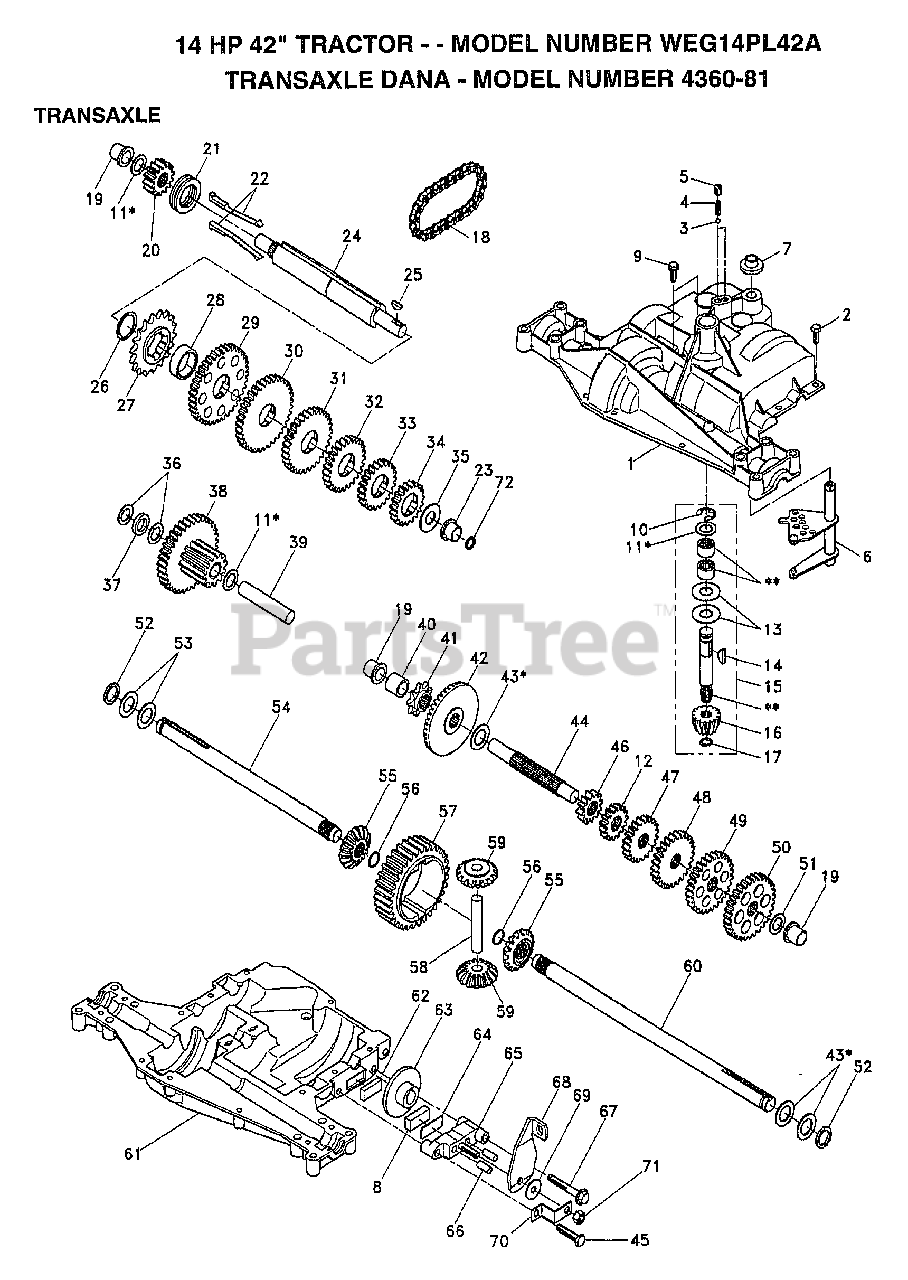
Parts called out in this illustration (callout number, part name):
1	HOUSING, UPPER
3	BALL, DETENT
4	SPRING, DETENT
5	SCREW, SET
6	KIT, SHIFTER ASSEMBLY
7	BOOT, SHIFTER
8	PUCK, FRICTION
9	SCREW TAPPING WITH SEALER
10	RING, RETAINING
11	ASSY, KIT, SHIM .625 SHAFT
12	GEAR, SPUR, 15T
13	WASHER, PLAIN .632 X 1.38 X .046
14	KEY, WOODRUFF, #9
15	ASSY KIT INPUT SHAFT
16	PINION BEVEL 14 TEETH
17	RING, RETAINING
18	CHAIN, 24 PITCHES
19	BEARING, FLANGE
20	GEAR, SPUR, 14 TEETH
21	COLLAR, CLUTCH
22	ASSY, KIT, CLUTCH KEYS
23	BEARING, FLANGE
24	SHAFT, INTERMEDIATE
25	KEY, WOODRUFF, #61
26	RING, RETAINING
27	SPROCKET, 18 TEETH
29	GEAR, SPUR, 37 TEETH
30	GEAR, SPUR, 35T
31	GEAR, SPUR, 30 TEETH
32	GEAR, SPUR, 25 TEETH
33	GEAR, SPUR, 22 TEETH
34	GEAR, SPUR, 19 TEETH
35	WASHER, PLAIN .640 X 1.37 X .061
36	WASHER, PLAIN .632 X 1.00 X .026
37	SPACER .630 X 1.00 X .169
38	ASSY GEAR COMB 12&35 TEETH
39	SHAFT, IDLER
40	SPACER .635 X .875 X .755
41	SPROCKET, 9 TEETH
42	GEAR, BEVEL, 42 TEETH
43	ASSY, KIT, SHIM .750 SHAFT
44	SHAFT, DRIVE
45	SCREW TAPPING
46	GEAR SPUR, 12 TEETH
47	GEAR, SPUR, 20 TEETH
48	GEAR, SPUR, 25 TEETH
49	GEAR, SPUR, 28 TEETH
50	GEAR, SPUR, 31 TEETH
51	WASHER, PLAIN .632 X 1.00 X .060
52	WASHER, NEOPRENE
53	WASHER, PLAIN .758 X 1.25 X .031
54	AXLE LEFT HAND
55	GEAR MITER 15 TEETH
56	RING, RETAINING
57	GEAR, SPUR, 32 TEETH
58	SHAFT, CROSS
59	GEAR, MITER, 15 TEETH
60	AXLE, R.H.
61	HOUSING, LOWER
62	PUCK, FRICTION
63	DISC, BRAKE
65	JAW, BRAKE
66	PIN, DOWEL
67	SCREW, SELF-TAPPING
68	LEVER ACTUATING
69	WASHER, PLAIN .321 X 1.00 X .055
70	BRACKET, ANTI-ROTATION
71	LOCKNUT 5/16-24
